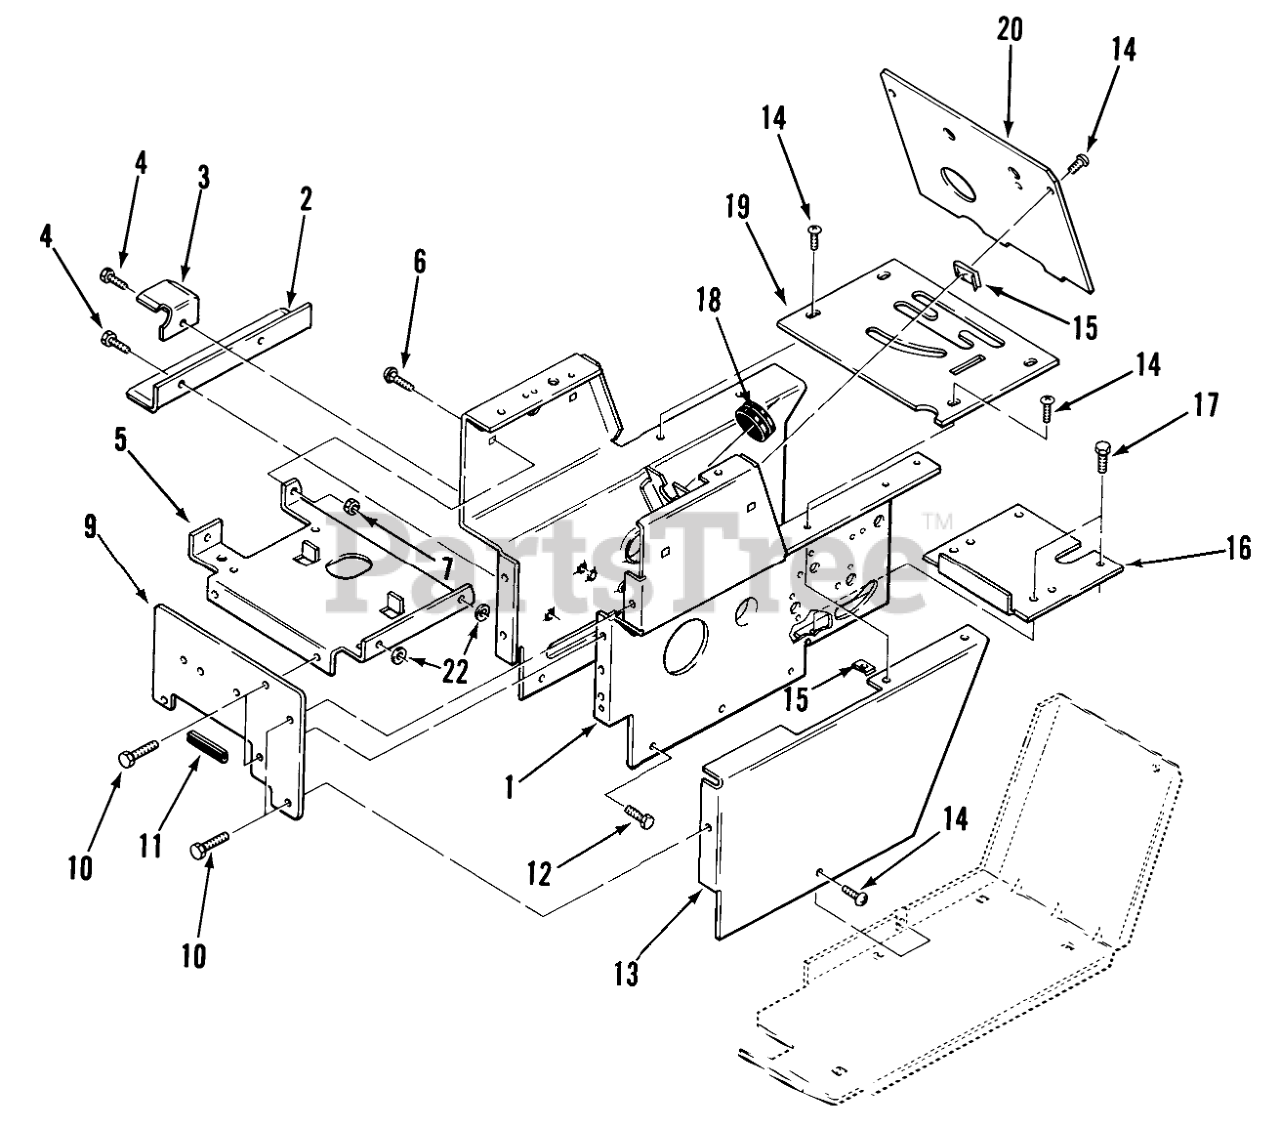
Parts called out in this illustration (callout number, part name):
1	Hoodstand
2	ANGL-BLT GURDB
3	BRCKET-BLT SUTB
3	Belt Bracket
4	SCREW
5	Battery Support Bracket
6	CARRIAGE BOLT -4
7	Nut
9	Front Plate
10	SCREW
11	EDGE TRIM 2" 102896
12	SCREW
12	Bolt
13	Side Cover LH
14	Screw
16	Cover-Dust
17	SCREW
18	GROMMET
19	PLATE-SHIFT
19	Shift Cover Plate GT-1100, GT-1600 Only
20	Hoodstand Plate
22	WASHER 5/16 SAE
